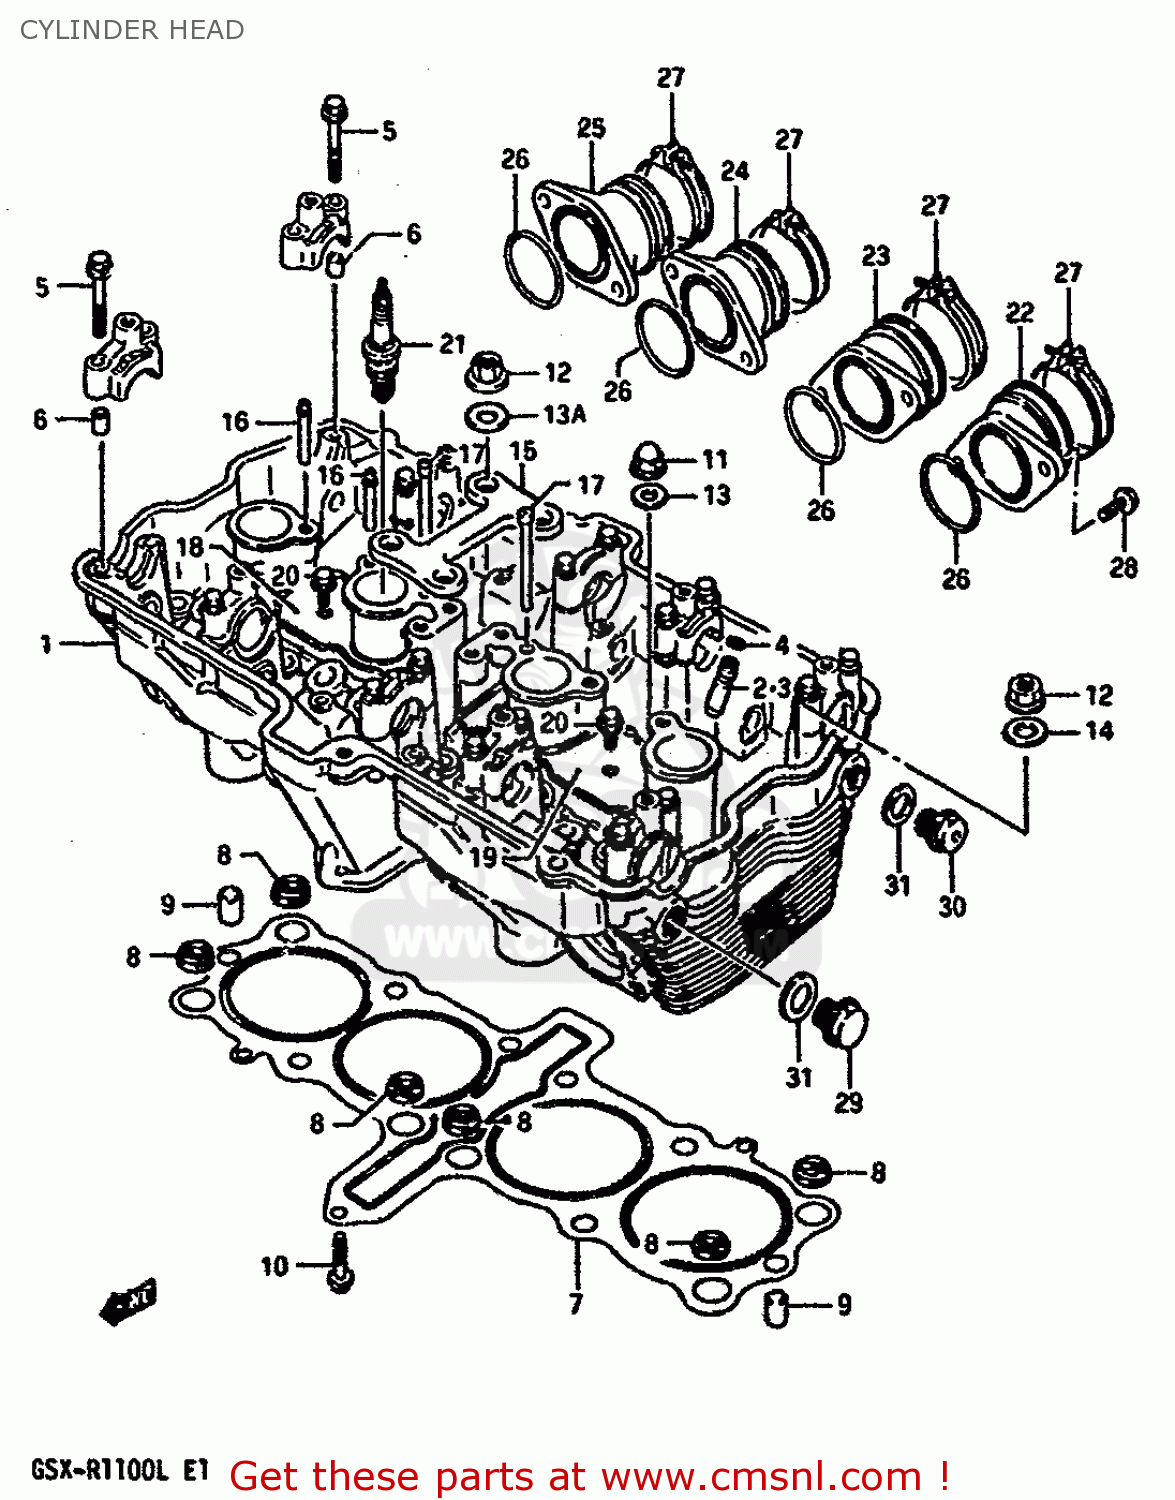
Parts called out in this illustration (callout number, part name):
1	HEAD ASSEMBLY,CYLINDER
2	GUIDE,VALVE
3	GUIDE,VALVE
4	RING,SNAP
5	BOLT(6X39)
6	PIN(6.2X8X11)
7	GASKET,CYLINDER HEAD (NAS)
8	O-RING,HEAD GASKET
9	PIN
10	BOLT
11	NUT
12	NUT
13	GASKET(10.2X20X2).3 (NAS)
13A	GASKET(10.2X20X2).3 (NAS)
14	WASHER (10.5X22X2.3)
15	PLATE,HEAD REINF
16	PIPE,OIL NO.1
17	PIPE,OIL NO.3
18	PLATE,OIL PIPE,R
19	PLATE,OIL PIPE,L
20	BOLT
21	PLUG,SPARK(JR9B)
22	PIPE,INTAKE
23	PIPE,INTAKE
24	NET,INTAKE
25	PIPE,INTAKE
26	O RING(D:2.4,ID:39.7)
27	CLAMP
28	SCREW
29	PLUG
30	PLUG
31	GASKET(14X19.2X2) (NAS)
